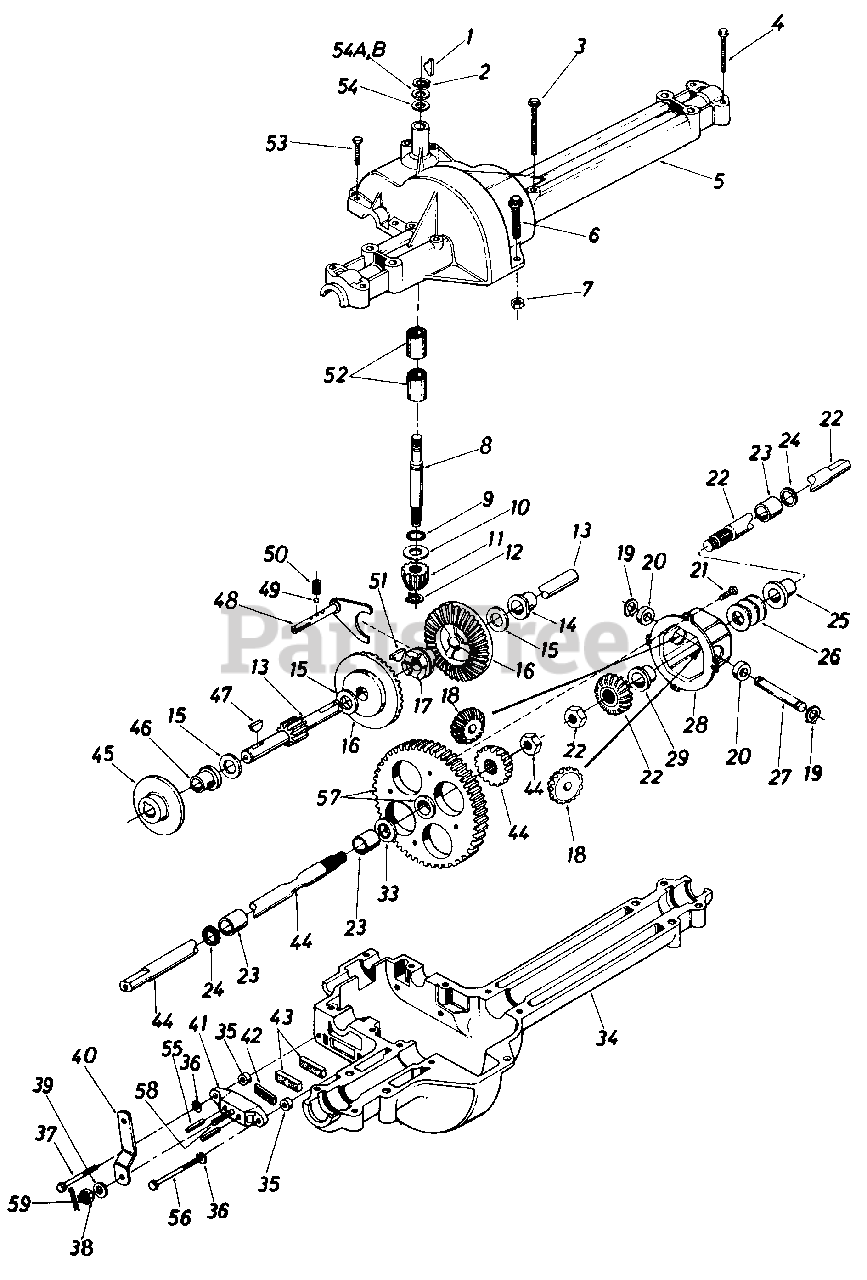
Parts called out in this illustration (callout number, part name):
1	#4 Hi-Pro Key 3/32 x 518" Dia.
2	Snap Ring .625" Shaft
3	Hex Bolt 1/4-20 x 1.75" Lg.
4	Hex Bolt 5/16-18 x 2.5"
5	Upper Housing
6	Hex Fl-Bolt 1/4-20 x .88" Lg.
7	Hex Nut 1/4-20 Thd.
8	Input Shaft
9	Square Seal 5/8" I.D.
10	Thrust Washer 5/8" I.D. x 1.25" O.D.
11	Pinion Input 14T
12	Retaining Ring 7/16" Ext.
13	Drive Shaft
14	Flange Brg. 5/8" I.D. x 3/4' Lg.
15	Fl-Wash.
16	Bevel Gear 42T
17	Clutch Collar
18	Miter Gear 15T (H.D.)
19	Snap Ring
20	Thrust Bearing 1/2" I.D. x 1.0" O.D.
21	Pan Head Scr. 1/4-20 x .50" Lg. w/Patch
22	Axle R.H. Ass'y.
23	Sleeve Bearing 3/4" I.D. x 1.0" Lg.
24	Oil Seal 3/4" I.D.
25	Flange Bearing 3/4" I.D. x 15/16" Lg.
26	Fl-Wash. .760n I.D. x l 49" O.D.
27	Cross Shaft
28	Differential Housing Ass'y.
33	Fl-Wash. 760" I.D. x 1.49" O.D.
34	Lower Housing
35	Spacer .53" O.D. x 3/8" Lg.
36	L-Wash. 1/4" I.D.
37	Hex Bolt 1/4-20 x 1.50" Lg. (Grade 5)
38	Castle Nut 5/16-24 Thd.
39	Fl-Wash. .344" I.D. x .875" O.D.
40	Actuating Arm
41	Brake Yoke
42	Puck Plate
43	Brake Puck
44	Axle L.H. Ass'y.
45	Brake Disc
46	Flange Bearing 5/8" I.D. x 15/16" Lg.
47	Woodruff Key 3/16 x 5/8 HT
48	Shift Fork Ass'y.
49	Ball Detent .250" Dia.
50	Spring Detent
51	#9 Hi-Pro Key 3/16" x 3/4" Dia. HT
52	Needle Brg. 5/8" I.D. x 1/2" Lg.
53	Hex Bolt 1/4-20 x 1.OO" Lg.
54	Fl-Wash. 5/8" I.D. x .030
54A	Fl-Wash. 5/8" I.D. x.040
54B	Fl-Wash. 5/8" I.D. x .020"
55	Actuating Pin 5/16" Dia.
56	Hex Bolt 1/4-20 x 2.50" Lg. (Grade 5)
57	Differential Gear 72T Ass'y. w/ Bearing
58	Sq. Hd. Bolt 5/16-24 Thd.
59	Cotter Pin 3/32" Dia. x .50" Lg.
